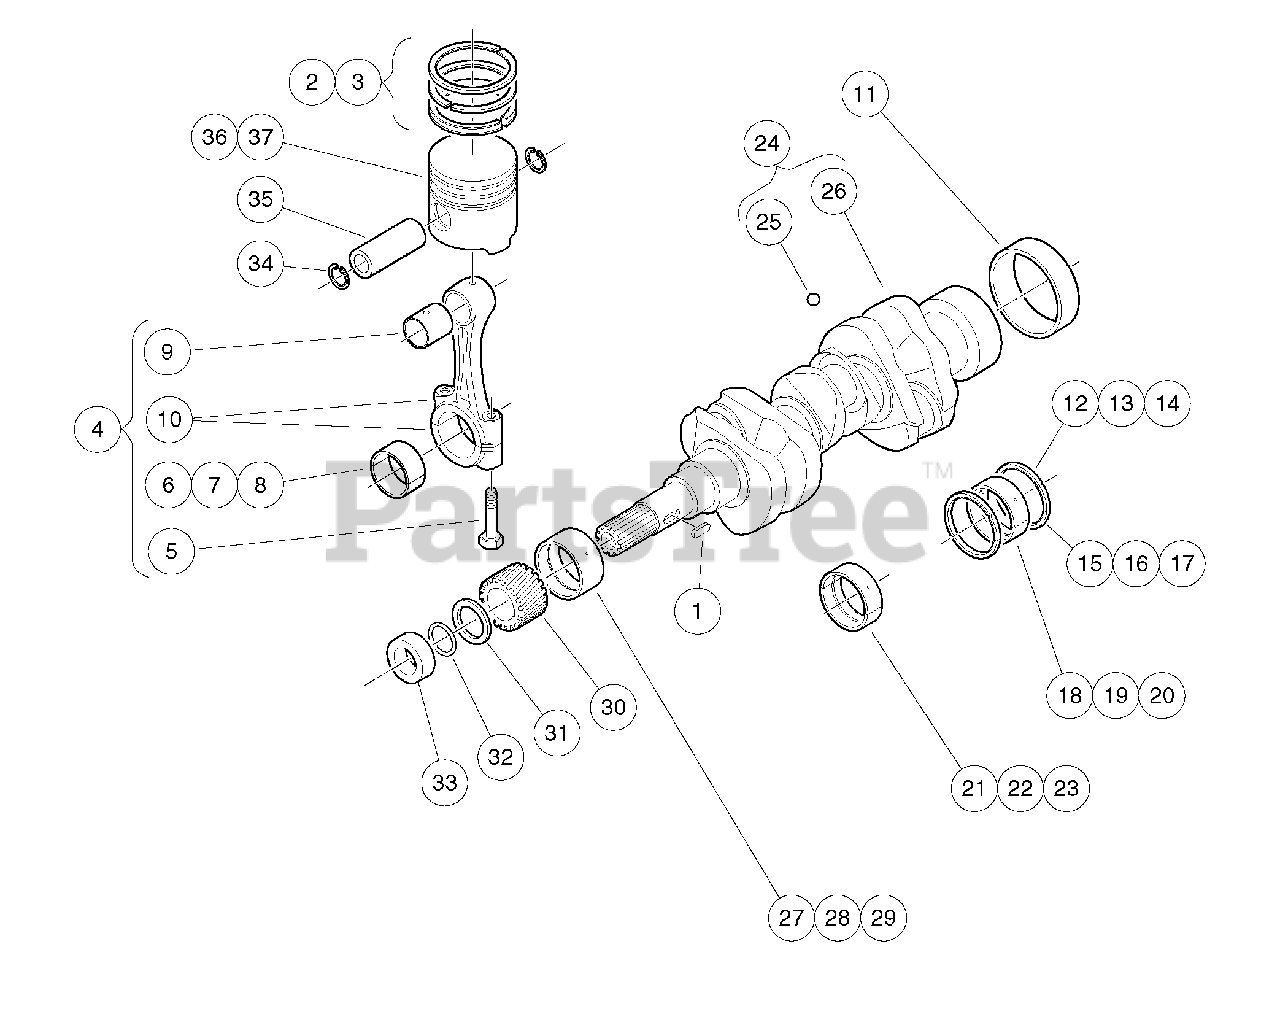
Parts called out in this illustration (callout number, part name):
1	Key, Feather, Short Camshaft
2	Assy Piston Ring, D722 Std
3	Assy Piston Ring, D722 +.025
4	Assy, Connecting Rod
5	Bolt, Connecting Rod
6	Metal, Crank, Rod, D722, Std
7	Metal, Crank, Rod, D722, .020
8	Metal, Crank, Rod, D722, .040
9	Bushing, Piston Pin, D722
10	Rod, Connecting
11	Sleeve, Crankshaft
12	Metal,crank, O Side, Std
13	Metal,crank, O Side, +.020
14	Metal,crank, O Side, +.040
15	Metal,crank, I Side, Std
16	Metal,crank, I Side, +.020
17	Metal,crank, I Side, +.040
18	Metal, Crank, Main, Rear Std
19	Metal, Crank, Main, Rear -.020
20	Metal, Crank, Main, Rear -.040
21	Metal, Crank, Main, Mid Std
22	Metal, Crank, Main, Mid +.020
23	Metal, Crank, Main, Mid +.040
24	Crankshaft
25	Ball, Crankshaft
26	Crankshaft
27	Metal, Crank, D722, Frnt, Std
28	Metal, Crank, 722, Frnt, -.020
29	Metal, Crank, 722, Frnt, -.040
30	Gear, Crank
31	Slinger, Oil
32	O Ring, 23 X 26
33	Collar, Crankshaft
34	Circlip, Piston Pin
35	Pin, Piston
36	Piston, D722, Std
37	Piston, D722, +0.25
